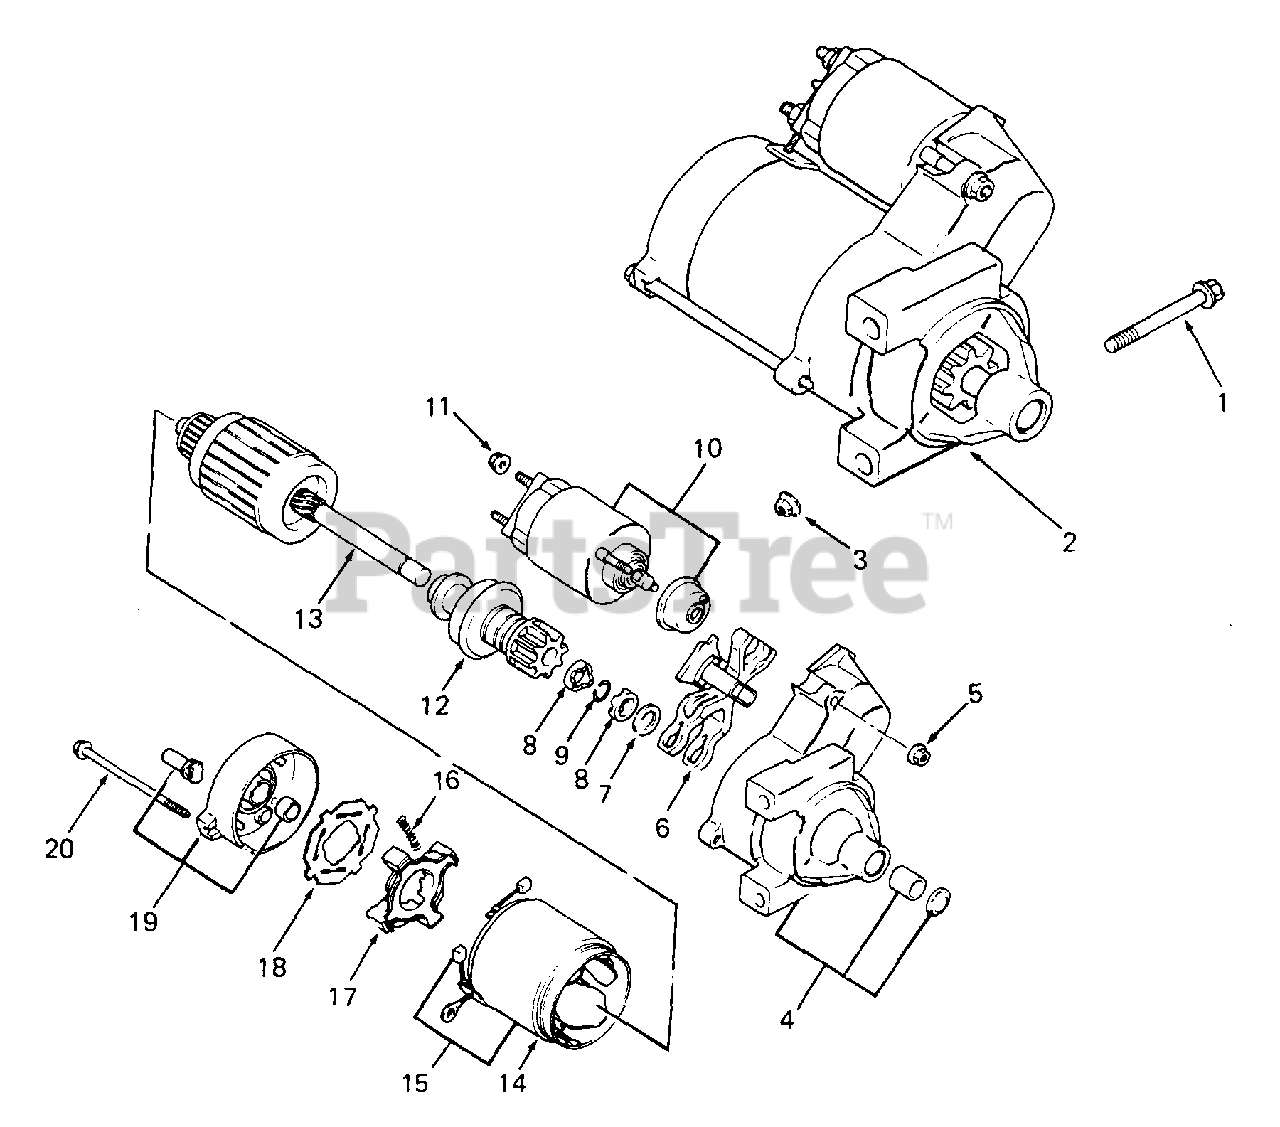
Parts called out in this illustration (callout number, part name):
1	Screw, M8 x 1.25 x 80
2	Starter, Solenoid Shift
3	Nut, M8 x 1.25
4	Nut, Starter
5	Drive, End Cap
6	Nut, Starter
8	Lever, Starter Drive
9	Washer, Thrust
10	Nut, Stop Collar
11	Ring, Retainer
12	Drive, Pinion
13	Armature, Starter
15	Kit, Brush & Spring
16	Spring, Brush
17	Holder, Brush
19	Commutator, End Cap
